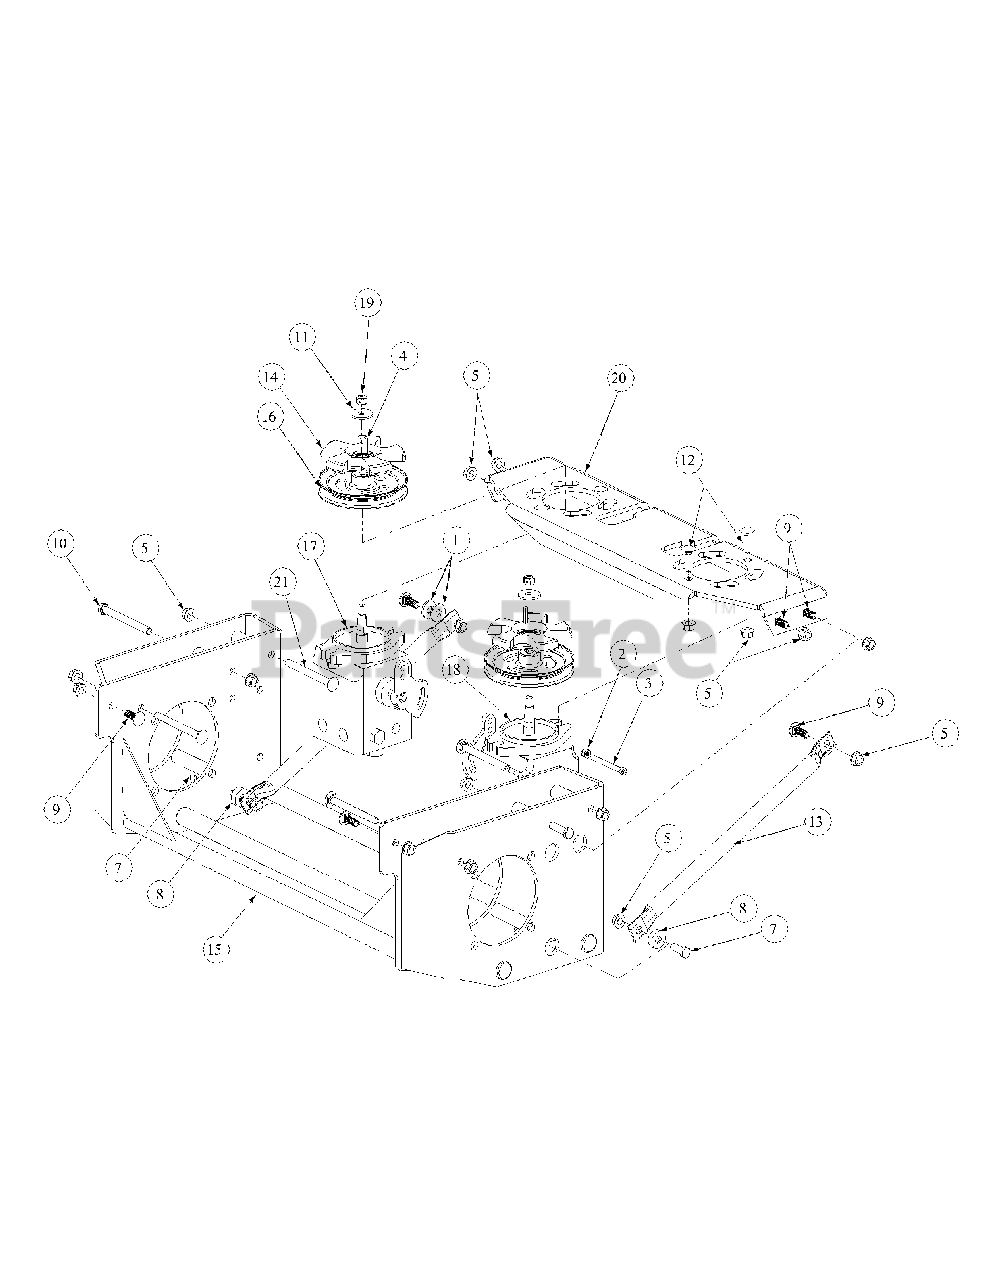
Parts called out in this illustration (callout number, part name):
1	Washer lock 3/8 zinc
2	Lock Nut, Nylon Insert, 1/4-20
3	Socket Head Cap Screw, 1/4-20 x 2-1/2
4	Key, 3/16" x 7/8"
5	Flange Lock Hex Nut, 3/8-16
7	Hex Cap Screw, 3/8 -16 x 1.25
8	Spacer, .406 ID x 1.00 OD x .38
9	Carriage Bolt, 3/8-16 x 1
10	Hex Cap Screw, 3/8-16 x 3.75
11	Flat Washer, .411 x 1.25 x .100
12	Carriage Screw, 3/8-16 x 1.25
14	Hydro Pulley Fan
15	Hydro Motor Frame Assembly
16	Hydro Pump Pulley
17	Hydro Pump, LH
18	Hydro Pump, RH
19	Hex Nut, 3/8-24
20	Hydro Pump Mount
21	Carriage Bolt, 3/8-16 x 4"
